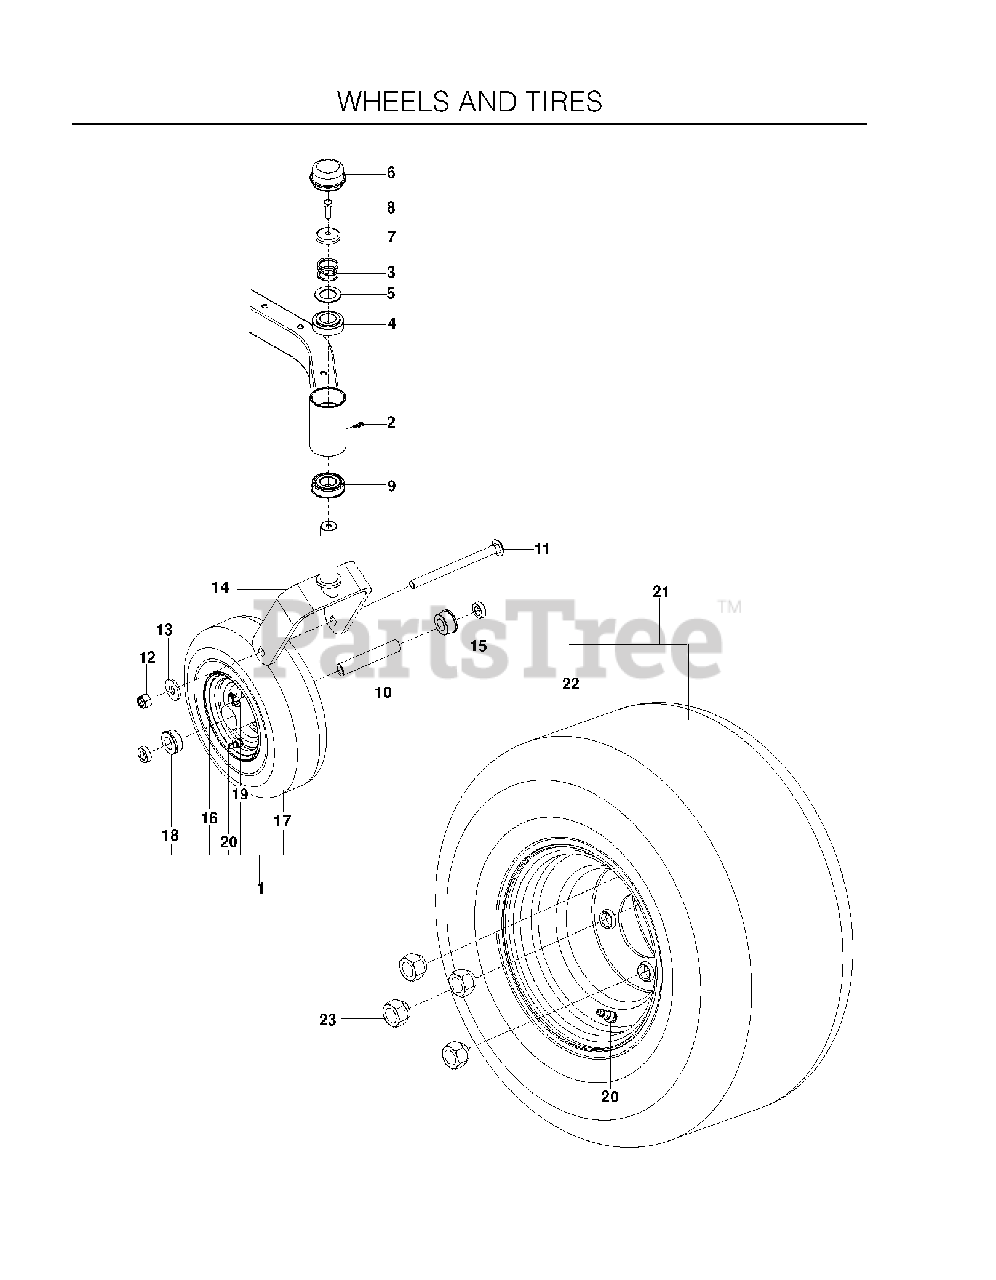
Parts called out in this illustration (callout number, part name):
1	TIRE, CASTER, ASSEM. 11X4-5, GR
2	ZERK, 3/16, DRIVE IN
3	SPRING, CASTER
4	BUSHING, CASTER
5	WASHER, 1.025 ID X 1.64
6	GREASE CAP
7	CASTER, PLUG
8	5/16-18X1 HHB G5W/NY
9	BEARING FLANGED
11	RHSNB 1/2-13 X 6.50 GR2 ZD
12	NUT 1/2-13 HEX CNTRLK GR 5 ZD
13	WASH USS FLAT 1/2
14	YOKE, CASTER, BLACK
15	SPACER, 5/16"
17	TIRE, 11"X4"-5.4 PLY, SMOOTH, KEND
18	BUSHING, WHEEL, 3/4"
19	ZERK
20	VALVE STEM TR-412
21	WHEEL ASM.18X8.5-8, KENDA
22	RIM, 8X7, SILVER, ZTR
23	LUG NUT 1/2F
